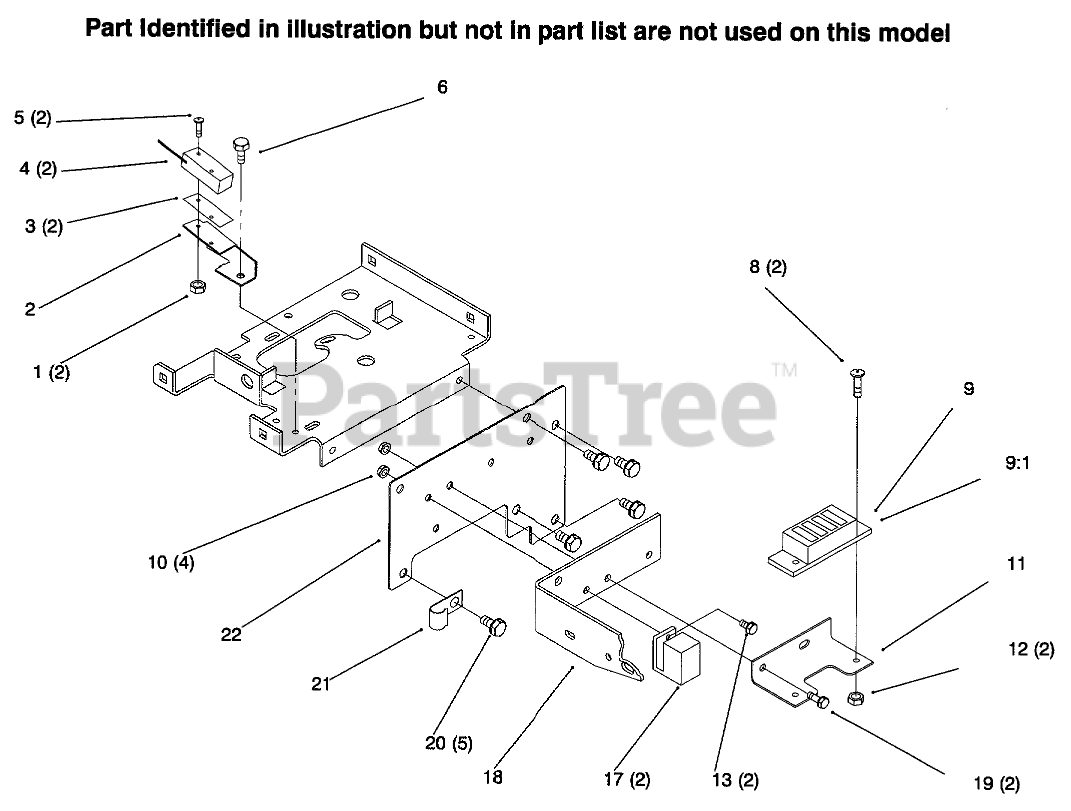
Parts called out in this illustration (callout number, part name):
1	NUT-HEX
2	BRACKET-SWITCH
3	BARRIER - SWITCH
4	SWITCH
5	SCREW-PHL 4-40X1 1/4
6	SCREW-HWH
8	SCREW-PAN
9	WIRING-HARNESS & DIA
9:1	FUSE-HOLDER 4 WAY
10	NUT-LOCK, NI
11	BRKT-FUS HLDERB
12	Nut
13	SCREW1/4-20X5/8 WHIZ
17	RELAY
18	BRACKET-BELTB
19	SCREW-HH
20	Bolt
21	CLIP
22	Front Plate
